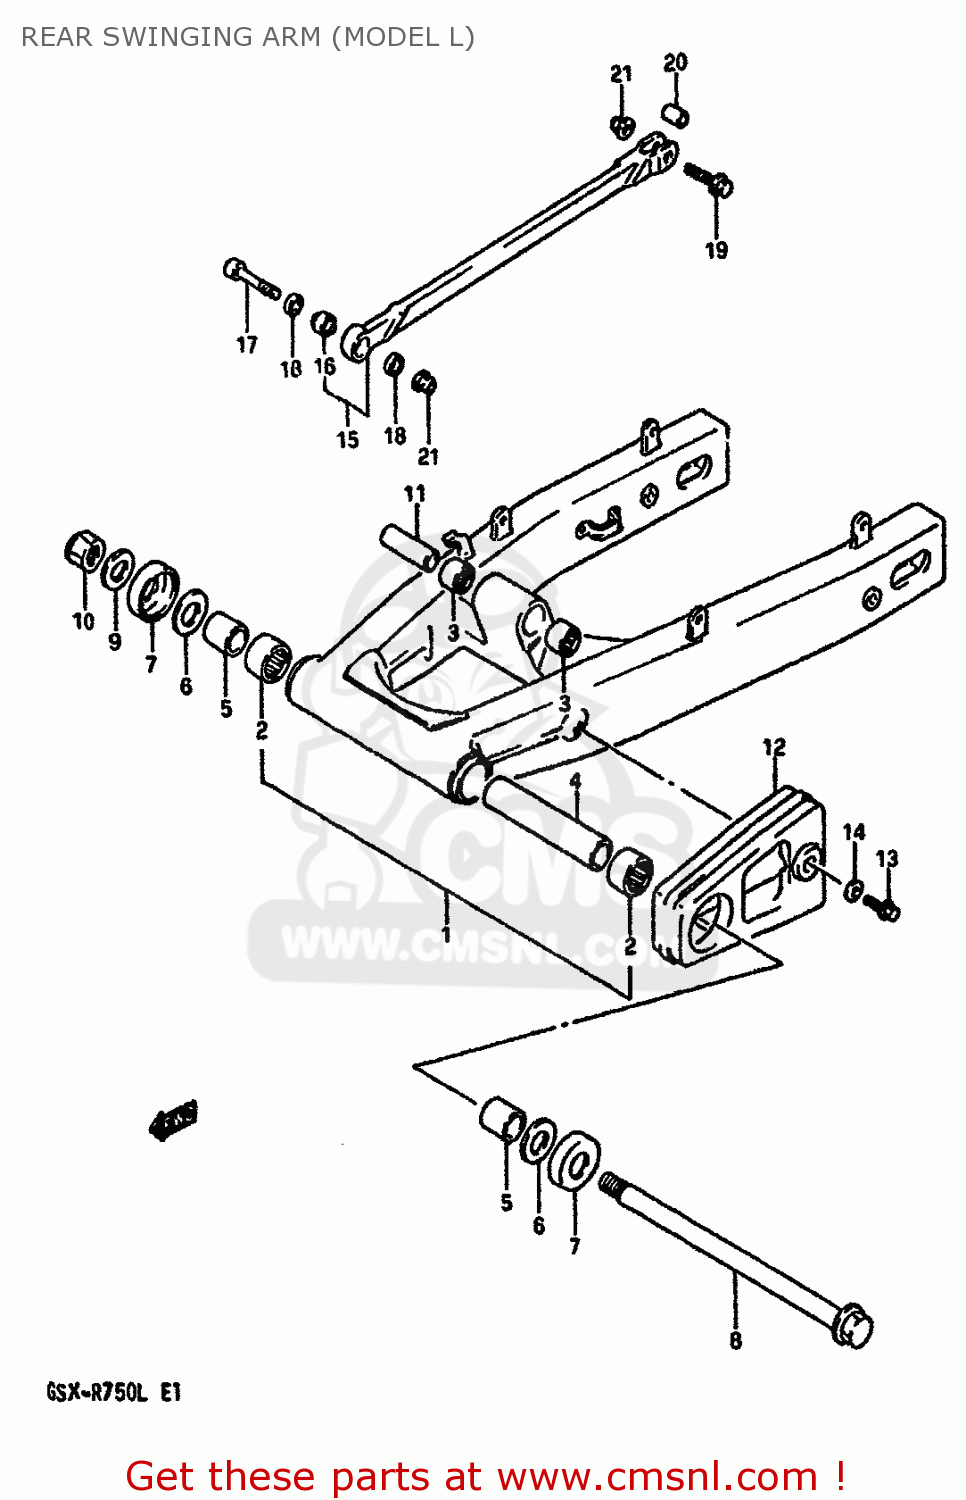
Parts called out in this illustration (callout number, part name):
1	SWING ARM ASSEMBLY,REAR
2	BEARING(25X33X30)
3	BEARING(20X27X23.5)
4	SPACER,RR SWGARM PIVOT CTR
5	SPACER,RR SWGARM PIVOT BERRING
6	WASHER
7	DUST SEAL,RR SWGARM PIVOT
8	SHAFT,REAR SWING ARM PIVOT
9	WASHER
10	NUT
11	BOLT,RR SWGARM PIVOT
12	NUT,REAR SWING ARM PIVOT
13	SPACER,RR CUSHION LEVER
14	BUFFER,CHAIN TOUCH DEFENSE
15	BOLT 6X20,WITH PLAIN WASHER
16	SPACER
17	TORQUE LINK SET,REAR
18	SPHERICAL BEARING,TORQUE
19	BOLT(8X48)
20	21
21	BOLT(8X38)
22	SPACER,RR TORQUE LINK RR
23	NUT
